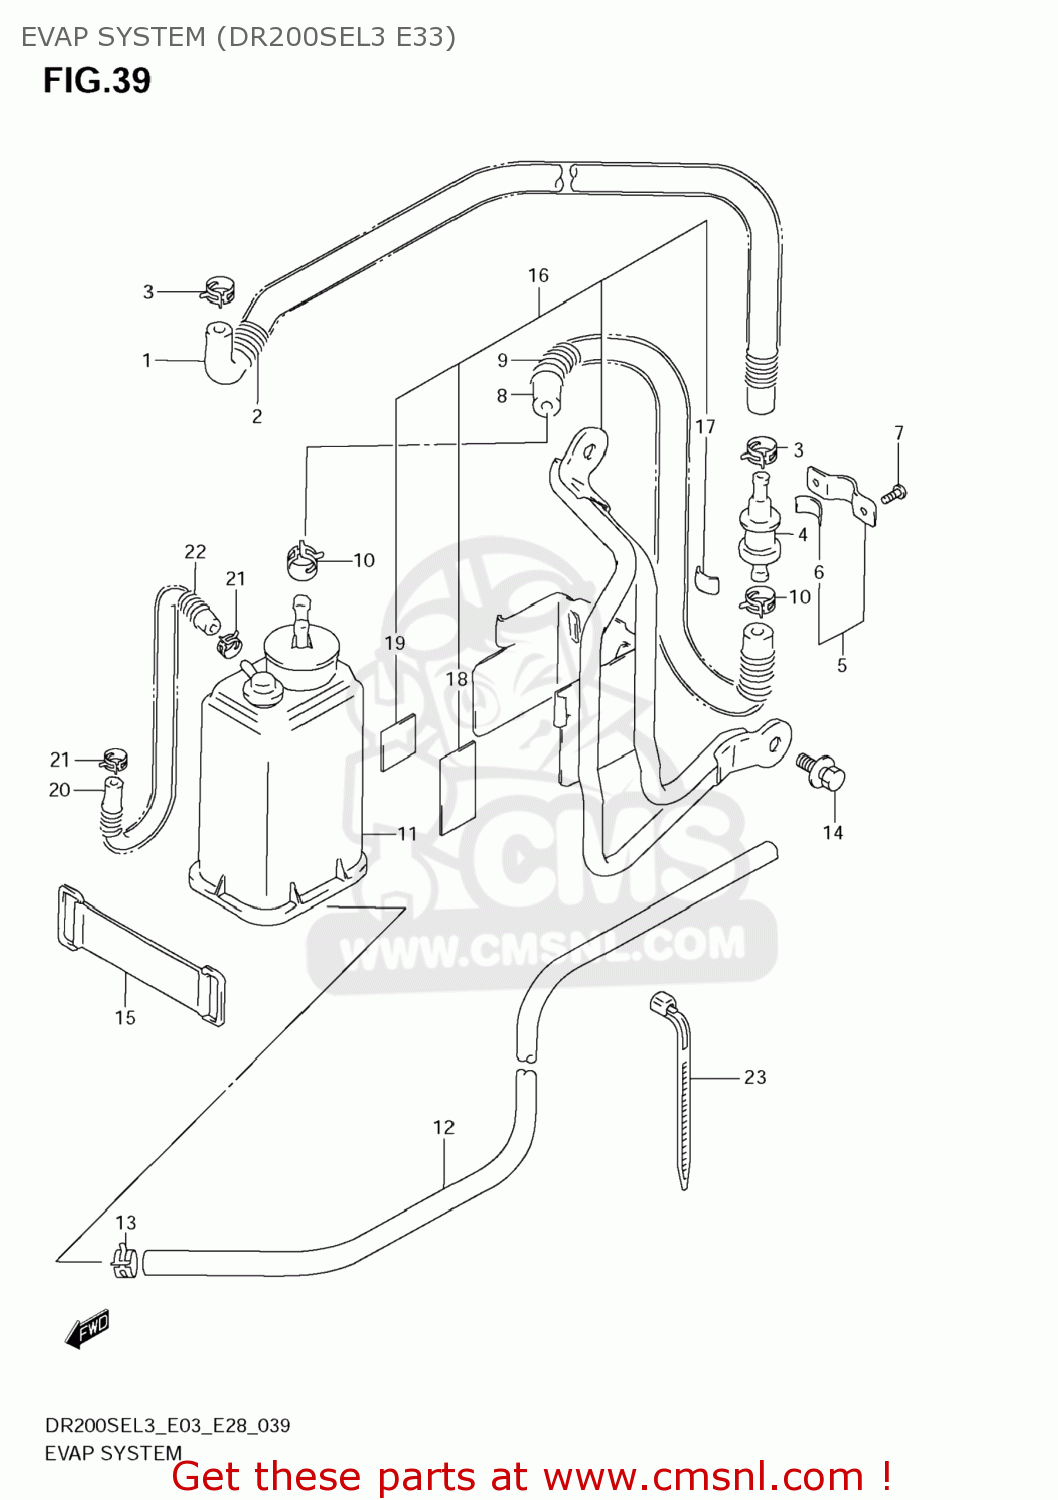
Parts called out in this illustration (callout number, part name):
1	HOSE,TANK & BREATHER VALVE
2	SPRING
3	CLIP
4	VALVE,FUEL TANK BREATHER
5	PLATE,FUEL TANK BREATHER NO.2
6	CUSHION
7	SCREW
8	HOSE,BREATHER VALVE & CANISTER
9	SPRING
10	CLIP
11	CANISTER ASSY,CHARCOAL
12	HOSE(7X11X2000)
13	CLIP
14	BOLT(6X16)
15	BAND
16	PLATE,CANISTER
17	CUSHION
18	CUSHION
19	CUSHION
20	HOSE,CSTR PURGE
21	CLIP
22	SPRING
23	CLAMP(L:125)
